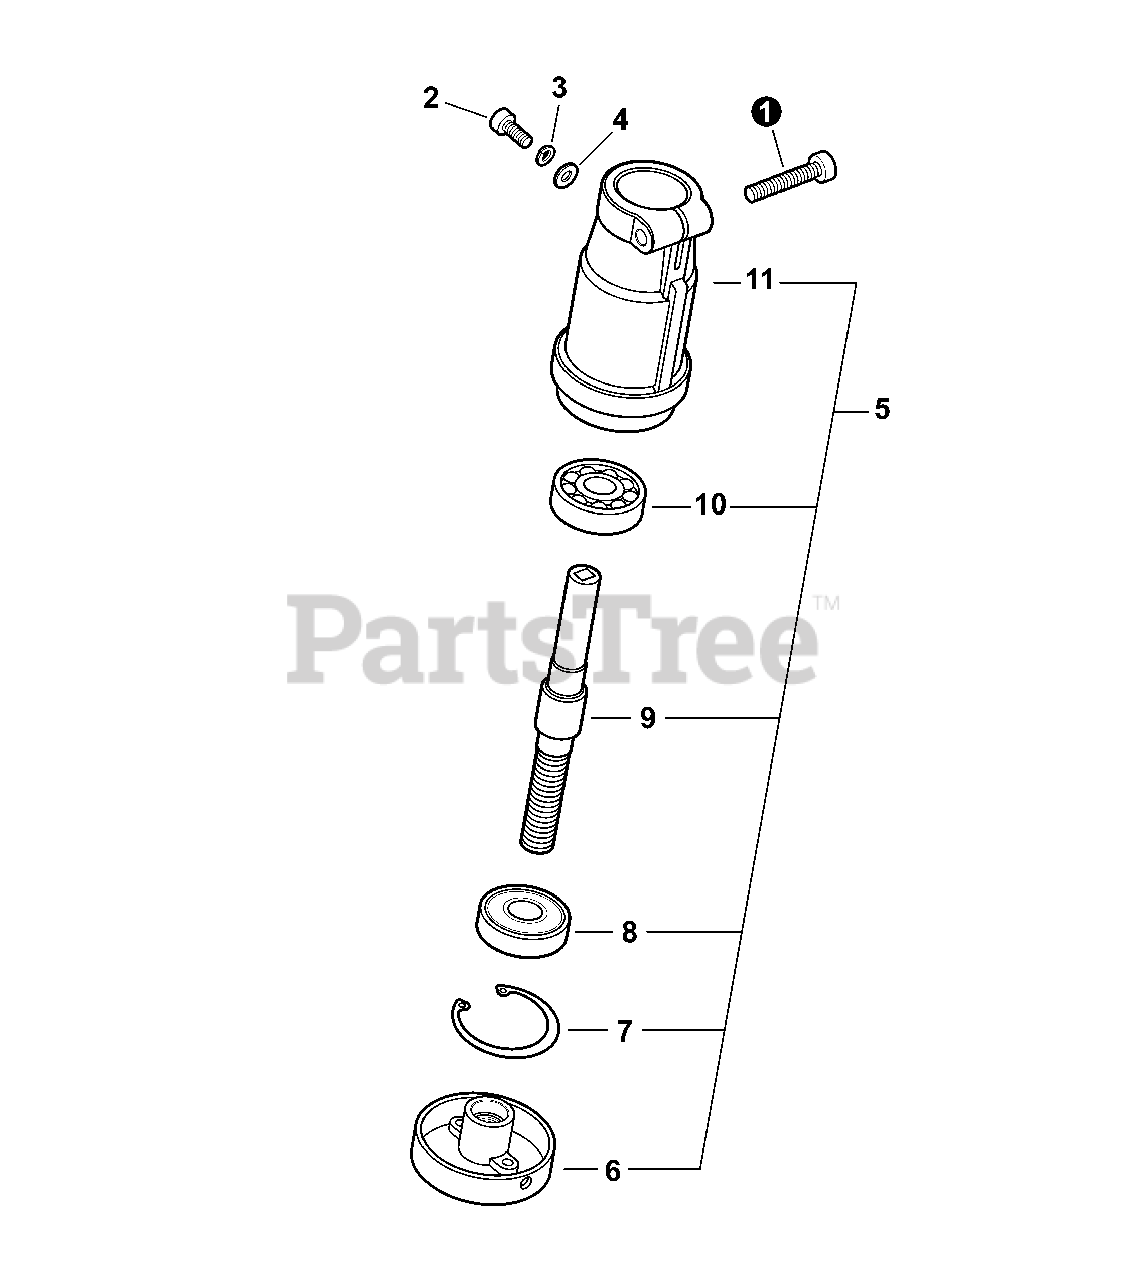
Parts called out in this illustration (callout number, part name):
1	BOLT, TORX 5×25
2	BOLT, TORX 4×10
3	WASHER, SPRING 4 MM
4	WASHER 4 MM
5	GEAR CASE ASSY
6	PLATE, ADAPTOR - UPPER
7	E-RING 30
8	BEARING, BALL 6200
9	SHAFT, GEAR
10	BEARING, BALL 6200
11	CASE, GEAR
